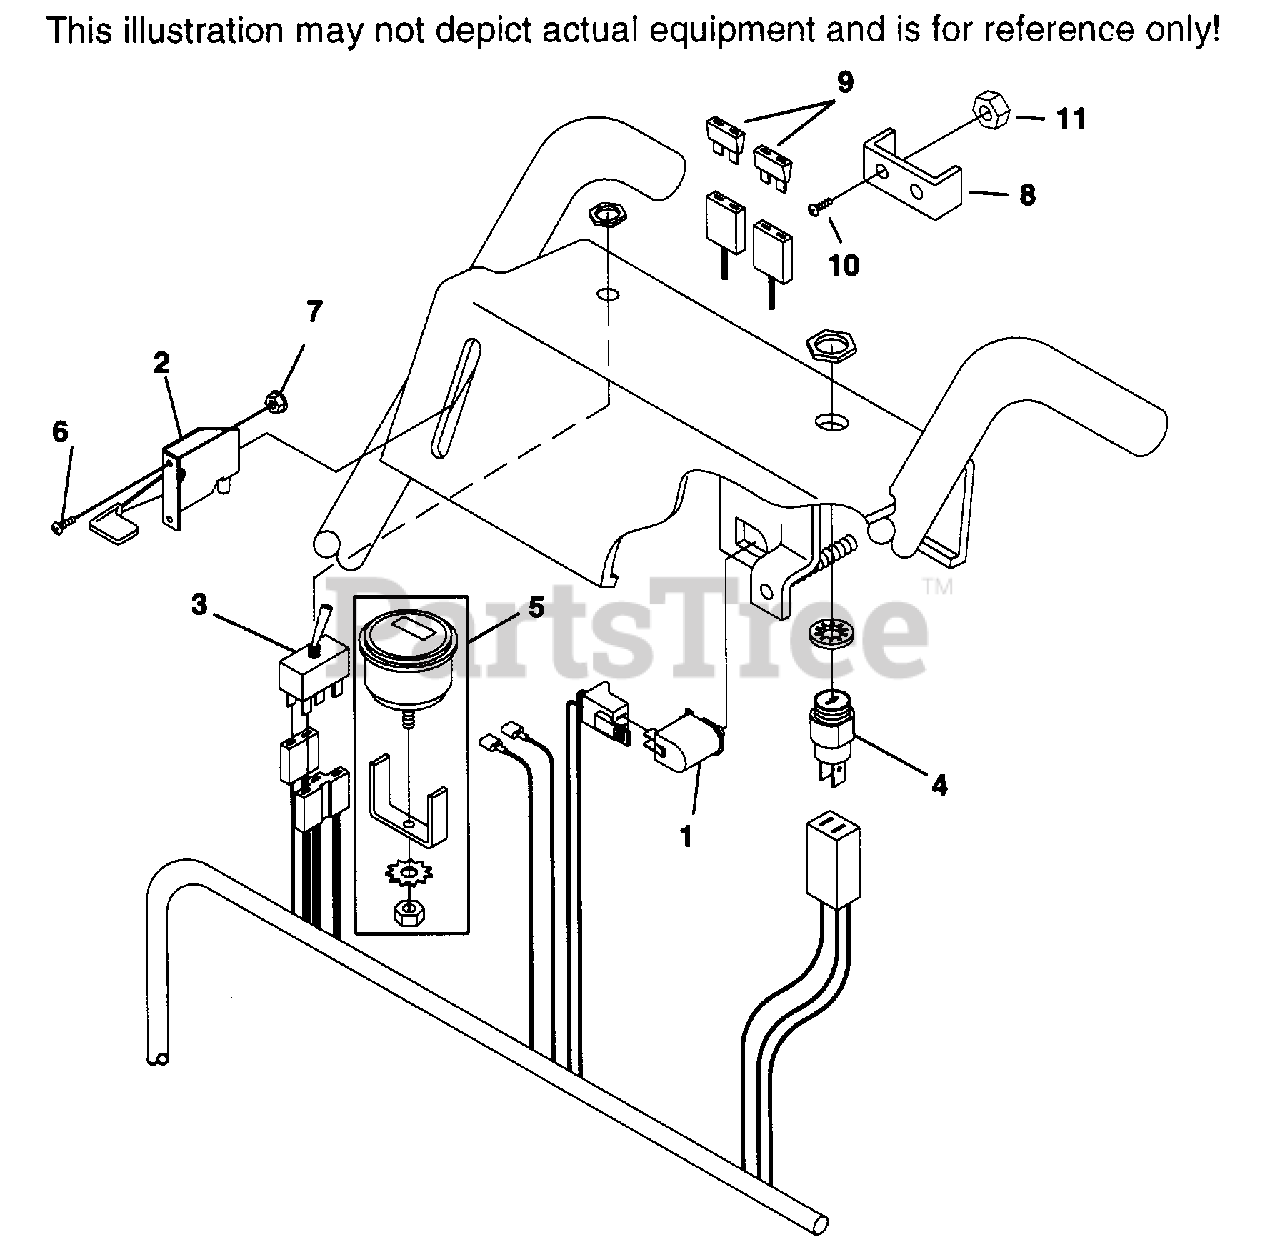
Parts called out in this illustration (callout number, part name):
1	SWITCH, NEUTRAL INTERLOCK
3	ENGAGEMENT SWITCH, ELECTRIC CLUTCH(INCLUDES
4	KEY SWITCH(INCLUDES HARDWARE)
5	HOUR METER(DEALER INSTALLED OPTION)
6	SCREW, #10-32 X .50 PHILLIPS WASHER HEAD
7	NUT, #10-32 SERRATED FLANGE HEX HEAD
NS	CLAMP, WIRE HARNESS
